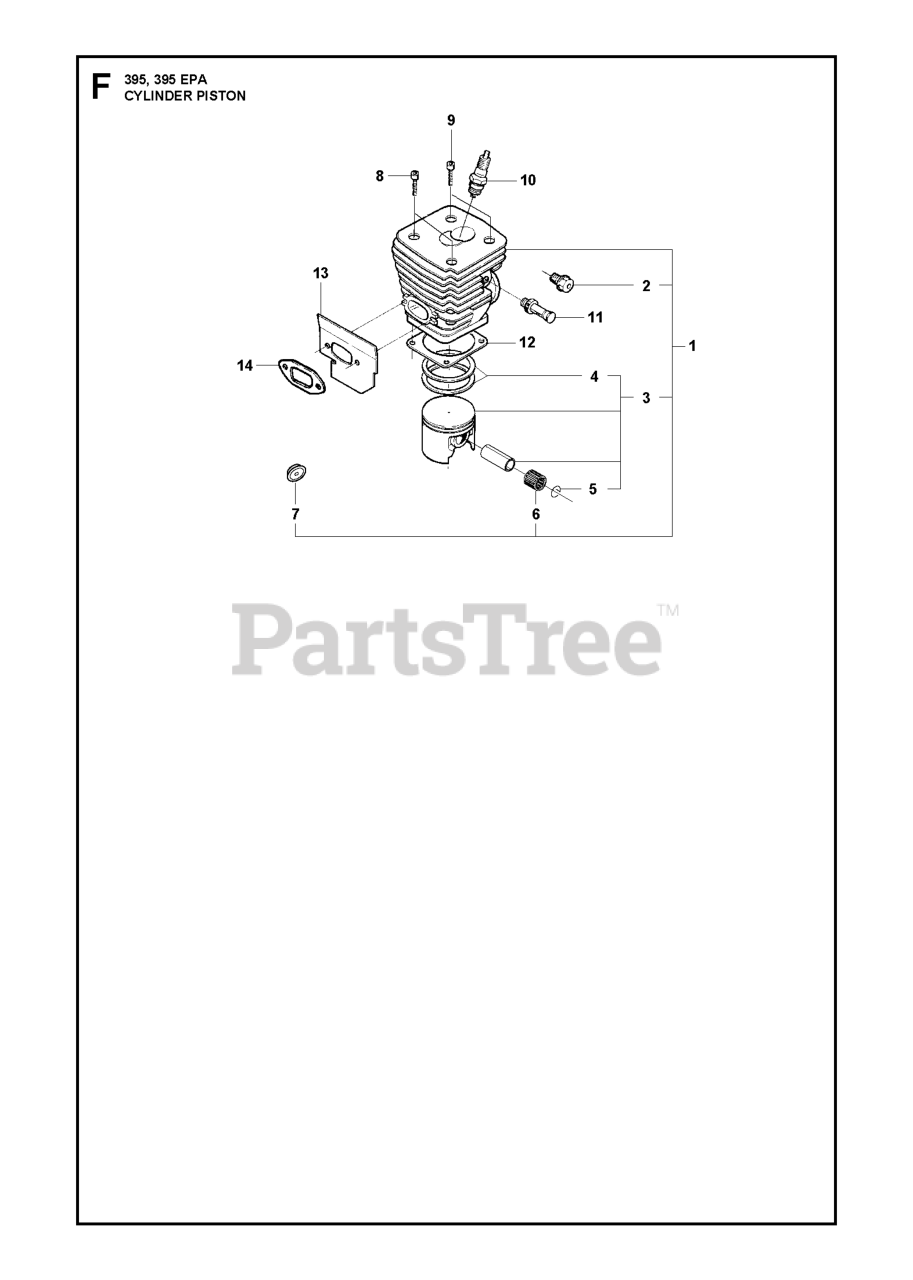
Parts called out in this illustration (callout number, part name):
2	CYLINDER PLUG
3	PISTON ASSY.
4	PISTON RING
6	SUPPORT BUSHING
10	SPARK PLUG RCJ6Y NLA
11	DECOMPRESSION VALVE
13	EXHAUST GASKET
